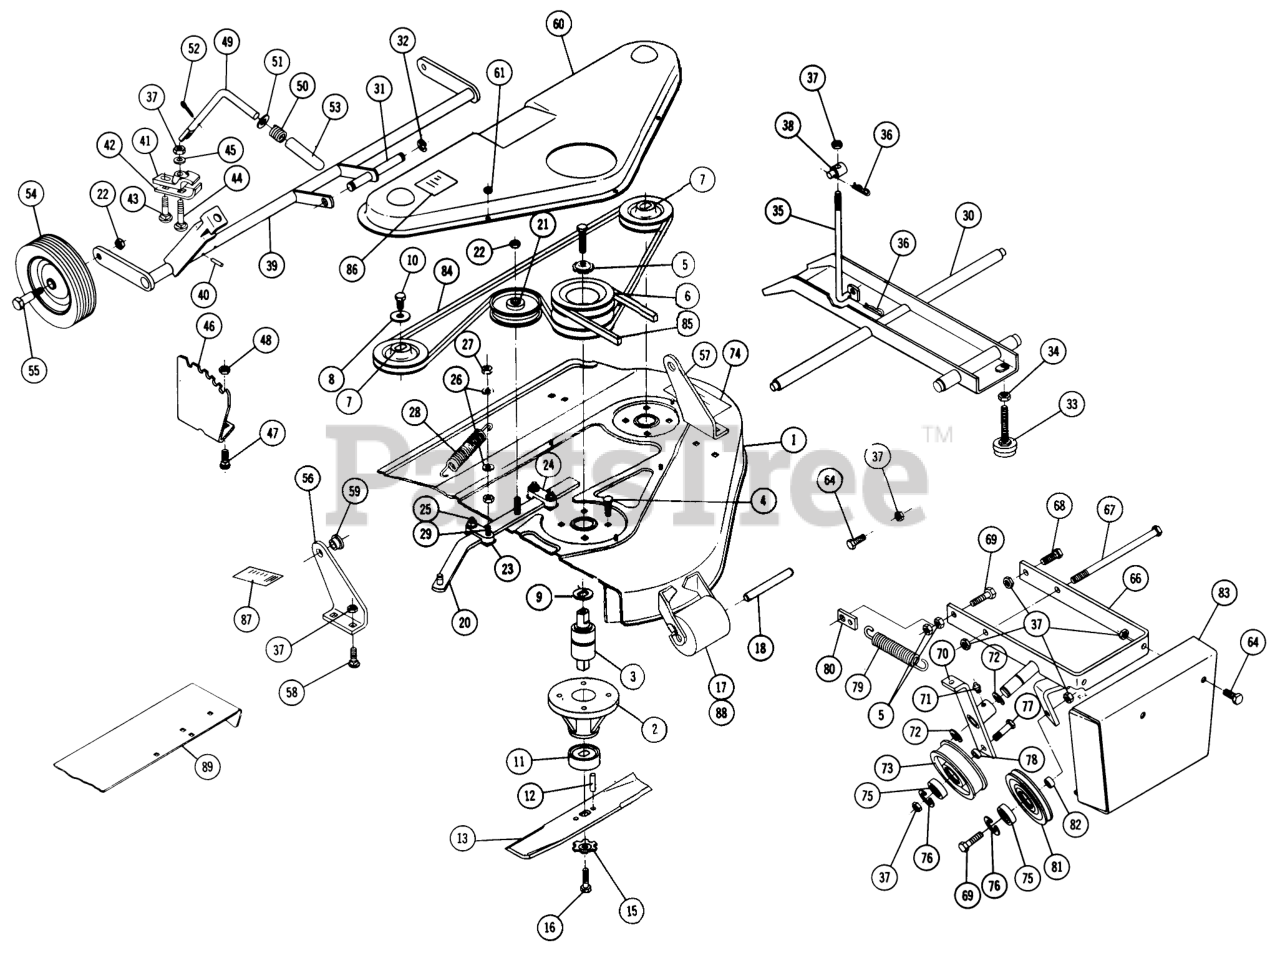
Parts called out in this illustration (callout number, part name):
1	Deck-Mower
4	Bolt Carriage 3/8-16 x 1
8	WASHER
9	WASHER
10	Bolt 3/8-16 x 3/4 Hex
12	SPIROL ROLL PIN
16	Bolt 3/8-16 x 7/8
18	Bolt-1/4-20 x 5/8
18	Nut-Nylok
22	3/8-16 Jam Nut
25	Bolt-5/16-18 x 1/4
26	Washer
27	Nut-Nylok
28	SPRING *R
29	Bolt-5/16-18 x 1 1/2
36	Hairpin
37	3/8-16 E.S.
38	TRUNNION-LIFT
40	Roll Pin
41	DISCONTIUNUED
43	Bolt Carriage 3/8-16 x 1
44	Bolt Carriage 3/8-16 x 2
45	Washer
46	Quadrant
47	Bolt Hex 5/16-18 x 3/4
48	Nut 5/16-18
51	Washer
52	Hairpin
53	GRIP
55	BOLT-SHOULDER
58	Bolt 3/8-16 x 1
59	BRONZE BUSHING
61	HEX NUT 10-32 E.S. + + USE 3296-21 + +
64	Bolt 3/8-16 x 1
67	Bolt-Hex 3/8-16 x 8
68	Bolt 3/8-16 x 1
69	Bolt Hex 3/8-16
72	E-RING
75	BEARING
76	INTERNAL SNAPRING
77	Bolt 3/8-16 x 1 5/8
79	SPRING-EXTENSION
82	SPACER
84	V-BELT
87	Decal-Height Adj.
87	Decal-36"
88	BUSHING
